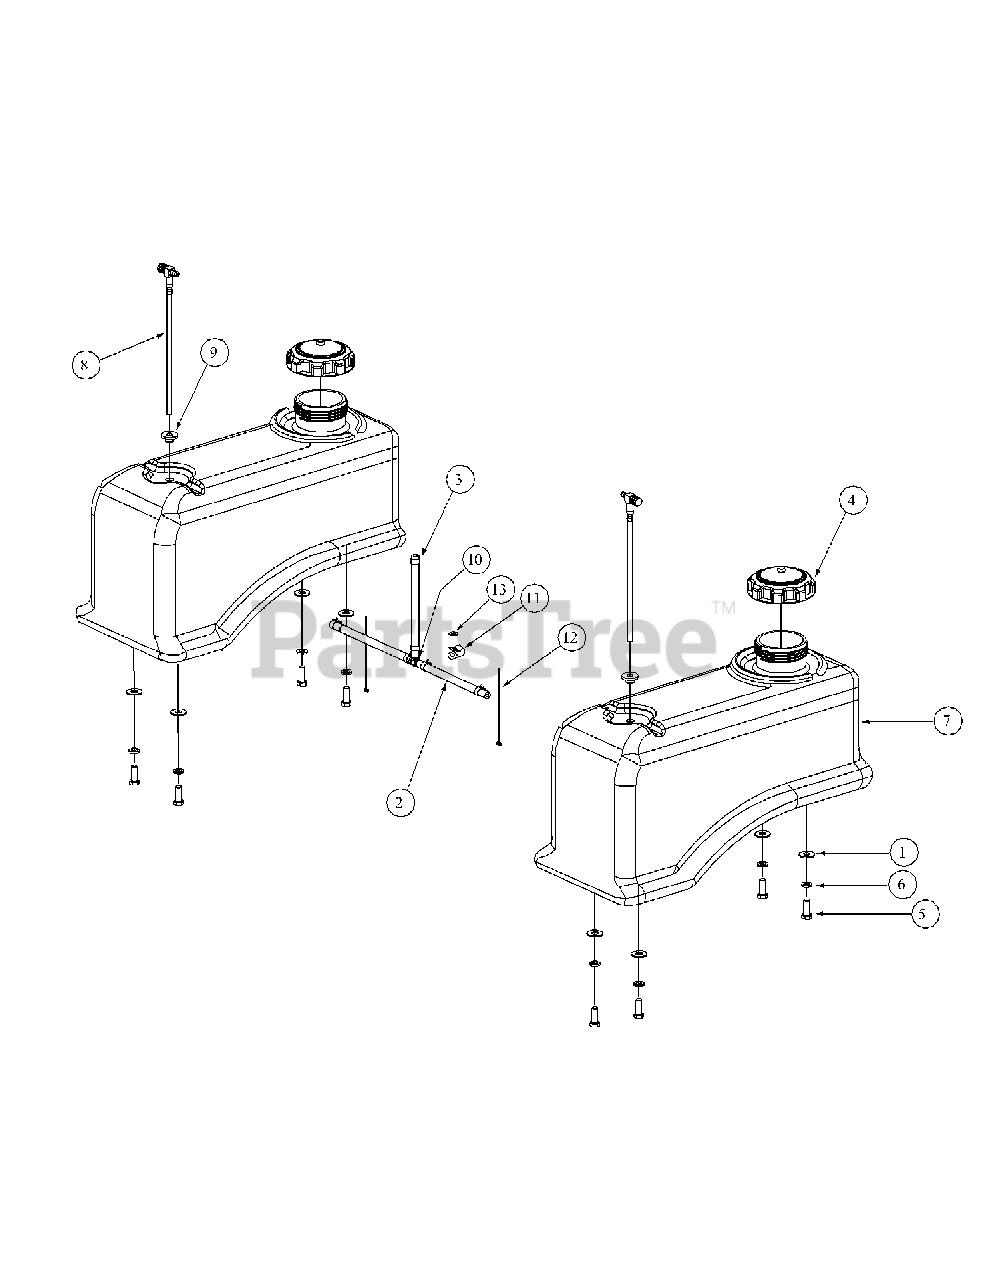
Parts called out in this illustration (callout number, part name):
1	Flat Washer, .406 ID, 1.0 OD, .105
2	Hose, 1/4" Fuel Line 79.5 inches
3	Clamp, Union
4	Fuel Cap, 3.5
5	Hex, Cap Screw, 3/8-16, .88
6	Lock Washer, 3/8
7	Fuel Tank
8	Fuel Fitting
9	Grommet, Fuel Tank
10	Tee Fitting, Fuel
11	Clamp, 1/2 Tubing
12	Cable Tie
13	Flat Washer, 1.4 x .630 x .0515
